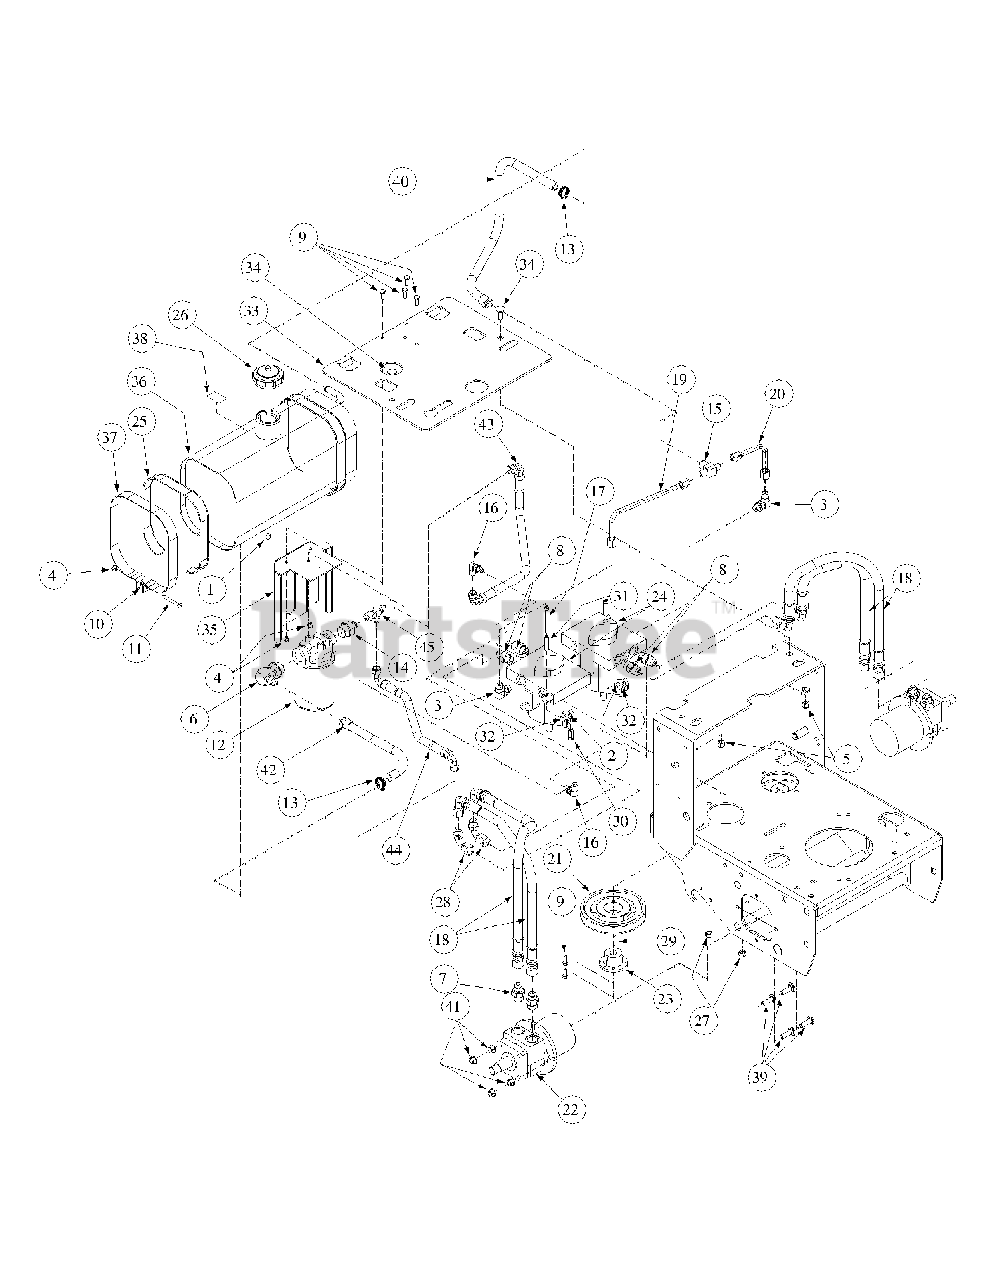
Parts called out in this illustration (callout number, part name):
1	Plug, 1/4"
2	Cap Screw, Standard, 3/8-16 x 1-1/4
3	Fitting, Aeroquip
4	Lock Nut, 1/4-20
5	Lock Nut, 3/8-16
6	Elbow 90° 1/2 x 3/4
7	Fitting, Aeroquip
8	Fitting, Aeroquip
9	Cap Screw, 1/4-20 x 3/4
10	Hex Nut, 1/4-20
11	Machine Screw, 1/4-20 x 2, Zinc
12	Filter Head 3/4
13	Clamp Wormgear, 5/16-7/8
14	Straight Connector 1/2 x 3/4
15	Fitting Aeroquip
16	Fitting, Aeroquip
17	Cap Screw, Socket Head, 1/4-20 x 2-1/2 Zinc
18	Hydro Hose Assembly, Reverse Pressure
19	Hydraulic Line, Pump Return Long
20	Hydraulic Line, Pump Return Short
21	Deck Pulley
22	Hydraulic Motor, Wheel
23	Bushing, 15mm Bore, Split, Type "D"
24	Pump Hydro BDP10L117
25	Pad, Oil Tank
26	Cap, Hydraulic Oil Tank
27	Lock Nut, 3/8-16
28	Fitting Aeorquip
29	Pump Key
30	Nut, Pump Release
31	Spacer, Pump Release
32	Washer, Idler
33	Fuel Tank, Mounting Plate
34	Carriage Bolt, 3/8-16 x 2
35	Filter Guard
36	Oil Tank w/Neck
37	Oil Tank Strap
38	Oil Label, 20W-50
39	Carriage Bolt, 3/8-16 x 1.25
40	Hose Assembly
41	Hex Nut, Flange Lock, 3/8-16
42	Hose, Filter to Tank
43	Hose, Filter to Left Pump
44	Hose, Filter to Right Pump
45	Fitting, Aeroquips
